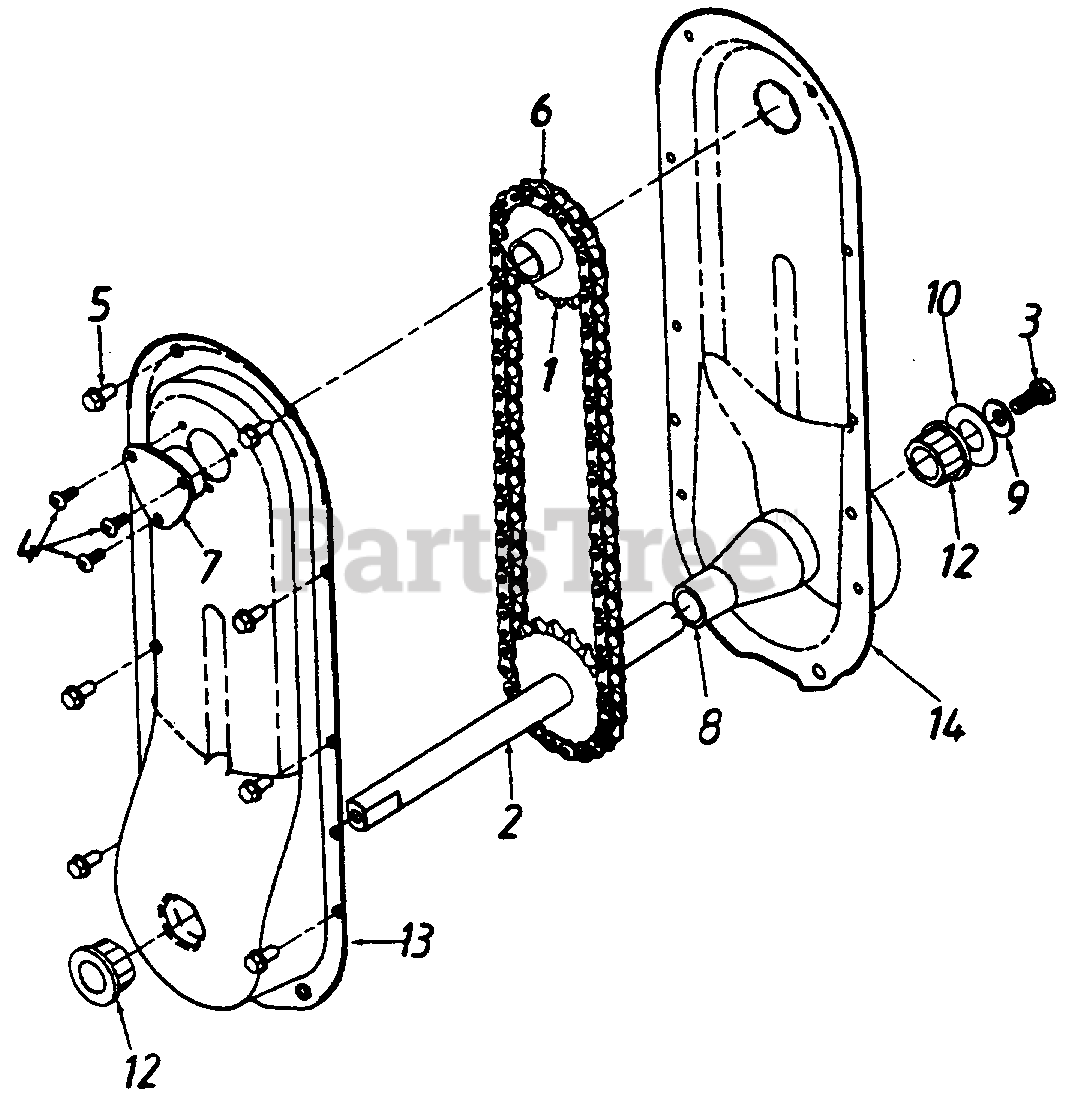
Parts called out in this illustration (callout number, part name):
1	Sprocket Ass'y. 17 Tooth
2	Shaft Ass'y. 19 Tooth
3	Hex L-Scr. 5/16-24 x .75" Lg.
4	Cross Recess Hd. B-Tap Scr. #10-16 Thd.
5	Hex Wash. Hd. Tap Scr. 1/4-20 x .5" Lg.
6	Chain #40 x 66 Links (Endless)
7	Axle Support Bearing
8	Axle Stop
9	Bell-Wash. .34" I.D. x .872" O.D.
10	Fl-Wash. .76" I.D. x 1.49" O.D.
12	Hex Flange Brg. .75" I.D.
13	Chain Case - Outer Half
